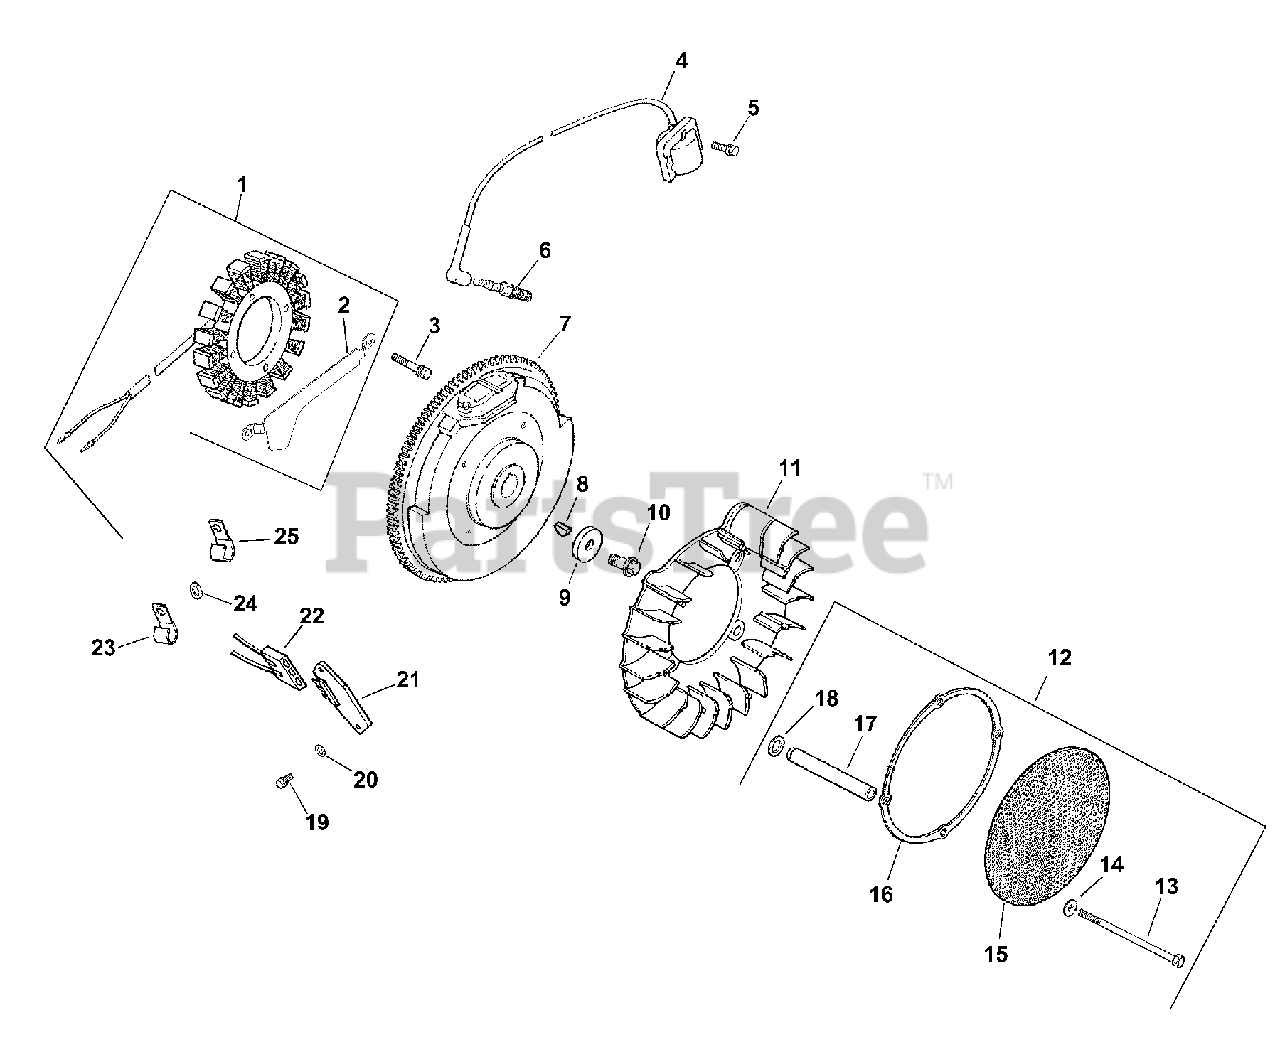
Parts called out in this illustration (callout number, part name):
1	STATOR KIT - USE 237878-S
2	BRACKET, STATOR WIRE
3	SCREW, M5X0.8X25 - (#25086402S)
4	MODULE, IGNITION-USE 24 584 45-S
5	SCREW, FLG THD FRM M5X.8X20-(#25086399S)
6	PLUG, SPARK (STD)
8	KEY, 3/16" X 5/8"
9	WASHER, FLAT 13/32"
10	SCREW, FLG M10X1.5X45 - (#25086361S)
11	FAN (KM)-USE 24 157 15-S
12	KIT, CHOPPER SCREEN
13	WASHER, SPRING 10 MM
15	RING, SUPPORT USE 25 141 08-S
16	SCREEN, GRASS-USE 24 162 41-S
17	WASHER, FLAT 1/4" (O.D. 1/2")
18	SCREW, CAP M6X1.0X99.5
19	SCREW, PHL HD #11-16X7/8"
20	WASHER, FLAT 3/16"
21	REG/RECT-15 AMP (KM)-USE 41 403 10-S
22	CONNECTOR, BODY (KM)-USE 25 155 41-S
23	CLIP, CABLE
24	WASHER, FLAT 1/4" (O.D. 1/2")
2451809-S	LEAD, OIL SENTRY
2546807-S	WASHER, FLAT 7/32"
